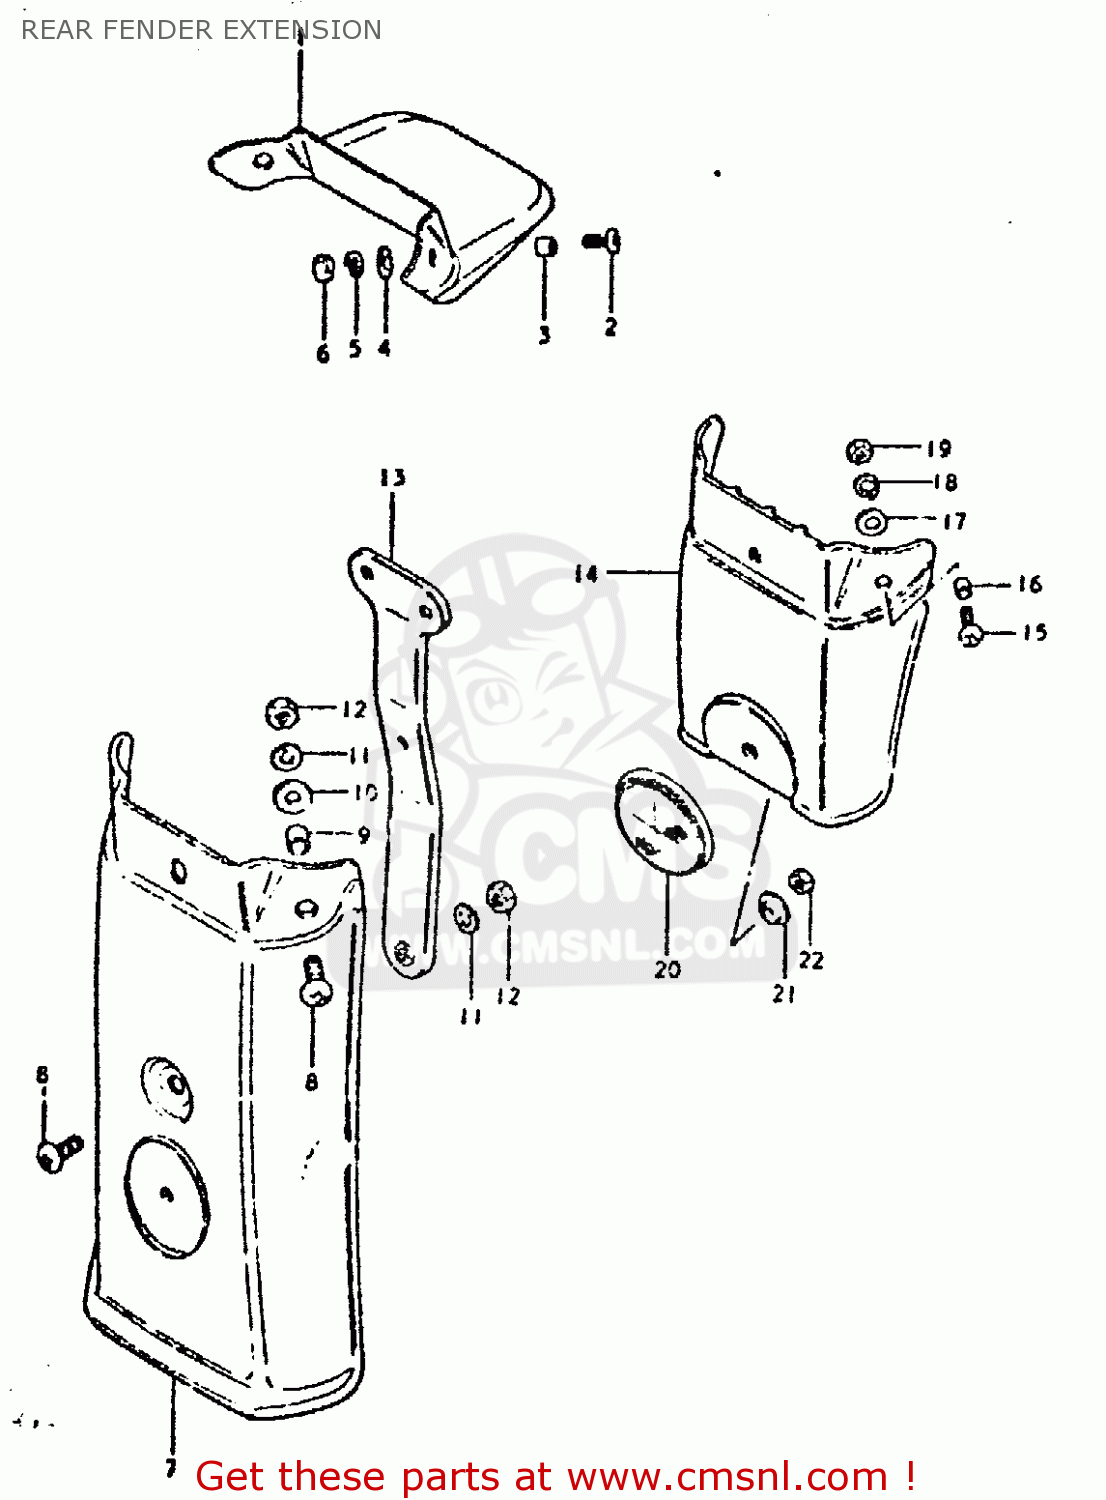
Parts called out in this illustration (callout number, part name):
1	EXTENSION,REAR FENDER
2	SCREW (6X15)
3	SPACER(6.2X8.3X5.7)
4	WASHER(6.5X18X1)
5	LOCK WASHER
6	NUT
